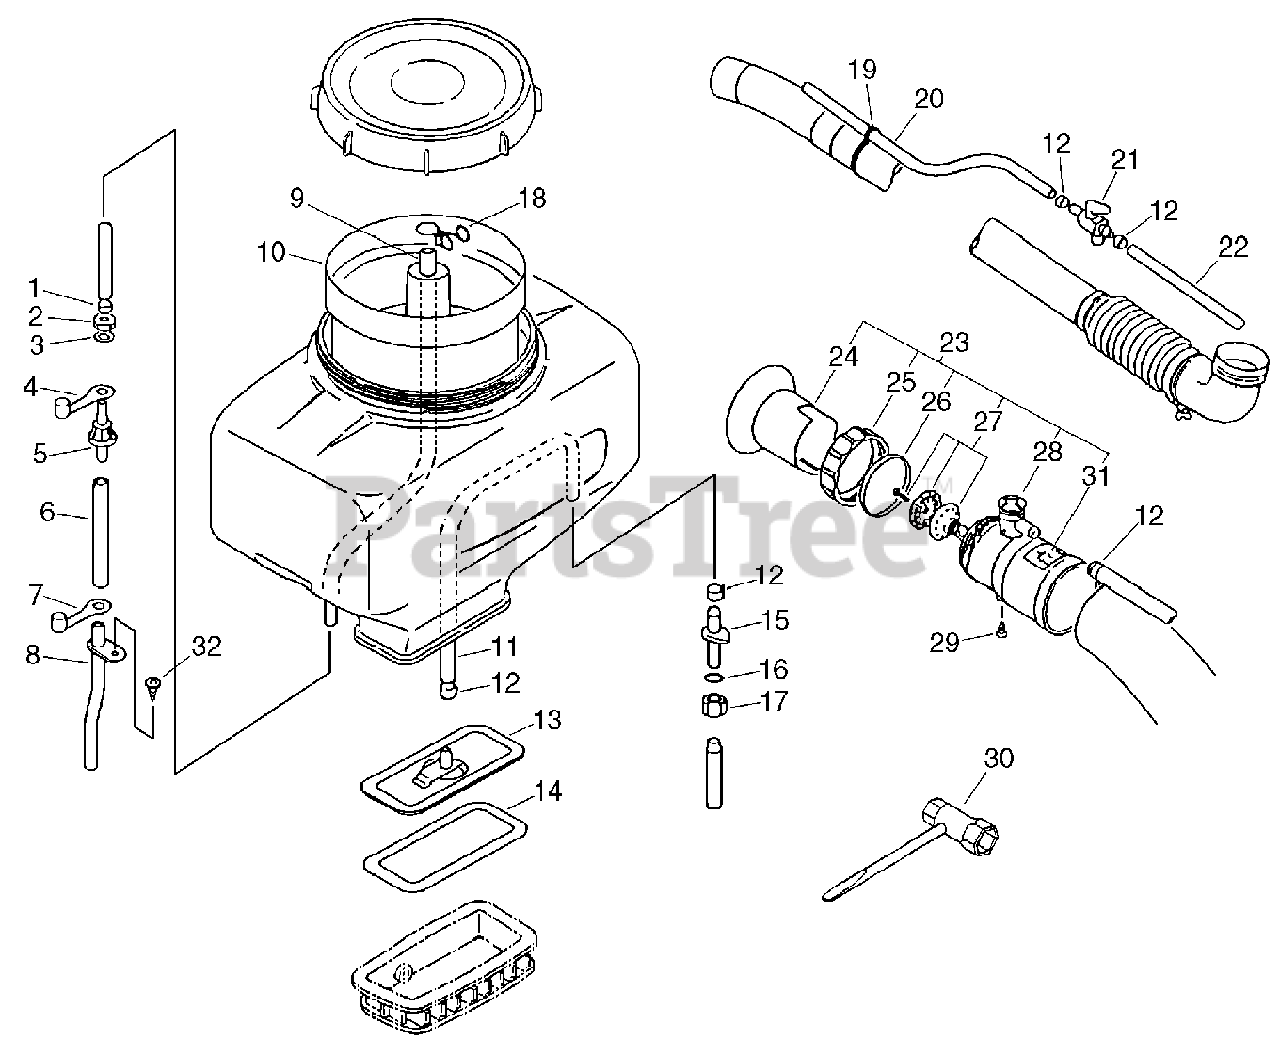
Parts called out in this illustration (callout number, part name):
2	NUT - 12
3	WASHER - 12
5	CONNECTOR, PIPE
6	PIPE, VENT - OUTER
8	PIPE - VENT
9	PIPE, VENT - INNER
11	TUBE, DISCHARGE
13	PLATE, DUST OUTLET
14	GASKET
15	CONNECTOR, PIPE
17	NUT, CONNECTOR
18	CLIP
20	PIPE - 650
21	VALVE
22	PIPE - 720
23	NOZZLE ASSY
28	CONTROL, VOLUME
29	SCREW - 5X12
30	T-WRENCH - 17X19mm
31	LABEL - MIST
32	SCREW - 5X16
